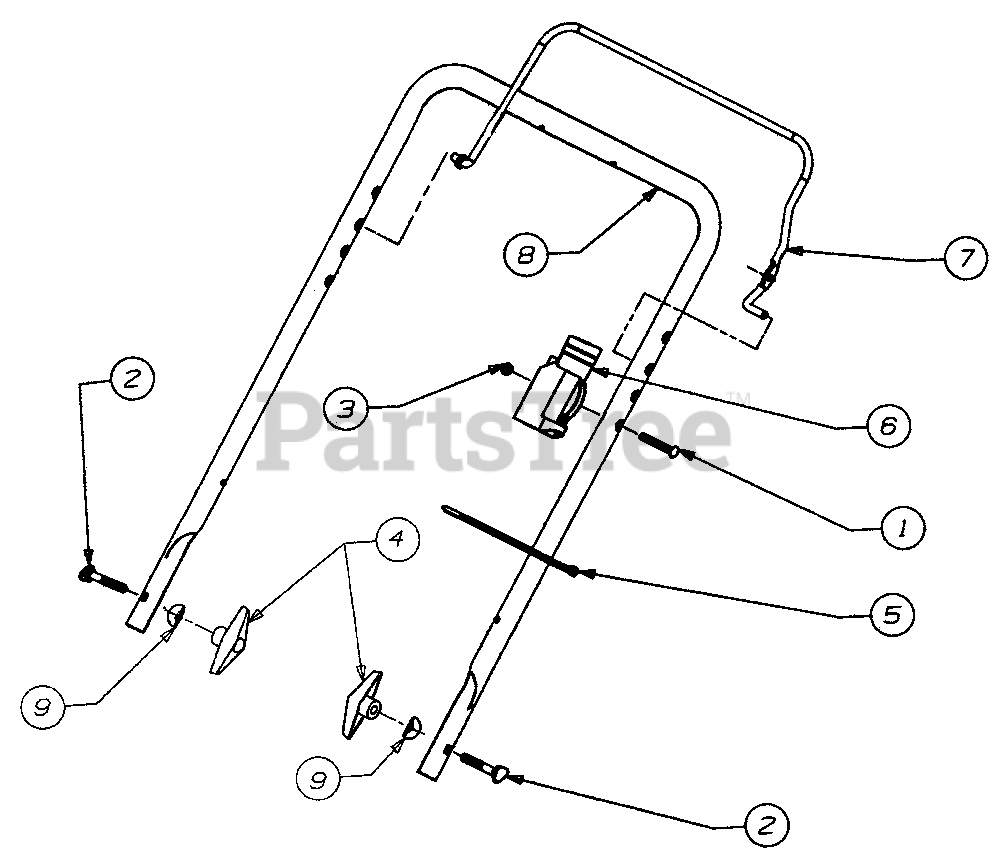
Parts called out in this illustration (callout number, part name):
1	Screw-Oval C-Sink L
2	Bolt Carriage
3	Nut Insl. Lock
4	Knob-Handle
5	Tie Cable
6	Body-Lever Control
